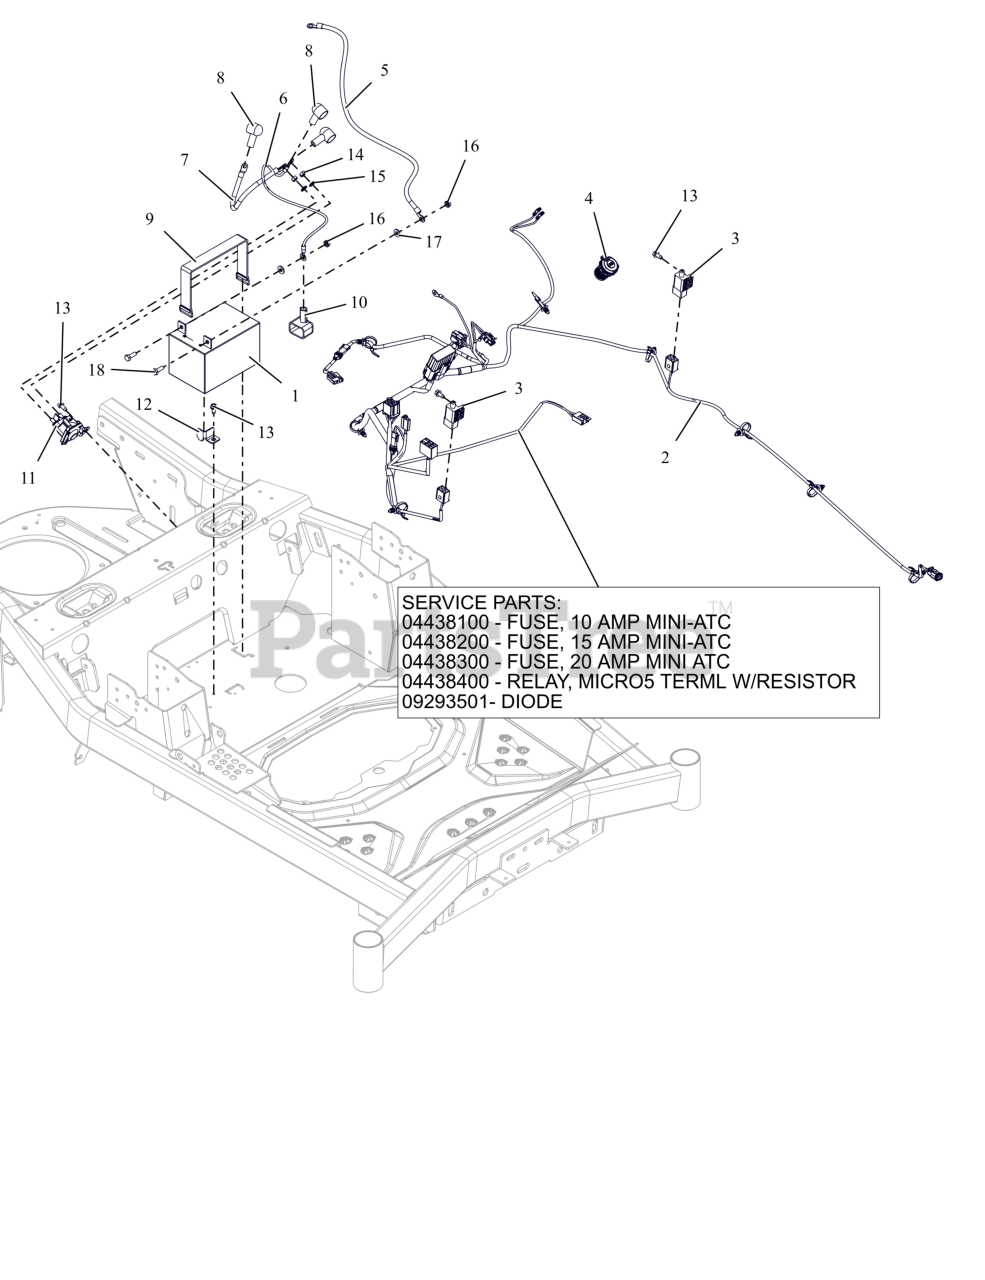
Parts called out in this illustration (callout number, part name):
1	BATTERY, 12V 12A -190CCA
2	HARNESS, MAIN IKON 23
2	FUSE,10 AMP MINI-ATC
2	FUSE,15 AMP MINI-ATC
2	FUSE,20 AMP MINI ATC
2	RELAY,MICRO5 TERML W/RESISTOR
2	DIODE, CONNECTOR SHELL
3	SWITCH-BRAKE NO/NO-POST & HOLE
4	USB, DUAL PORT USB-C, 12V BLK
5	CABLE-NEGATIVE BATTERY 24.00"
6	CABLE,POS W/2 1/4 RING 18.5 LG
7	CABLE, POS W/(2)1/4 RING 9.0LG
8	BOOT, EYELET TERMINAL
9	STRAP- RUBBER
10	INSULATOR
11	SOLENOID, STARTER (SEALED)
12	RETAINER, BATTERY CORNER (BLACK)
13	SCR-TAP .25-20X.50 HWH ZCC
14	NUT-STD M6-1.0 ZCC
15	WSHR,LK-EXT.262X.502X.026 ZCC
16	NUT-KEPS .250-20 ZCC
17	WSHR,FLT .281X.625X.065 ZCC
18	BLT, HEX .25-20X.75 G5 ZCC
